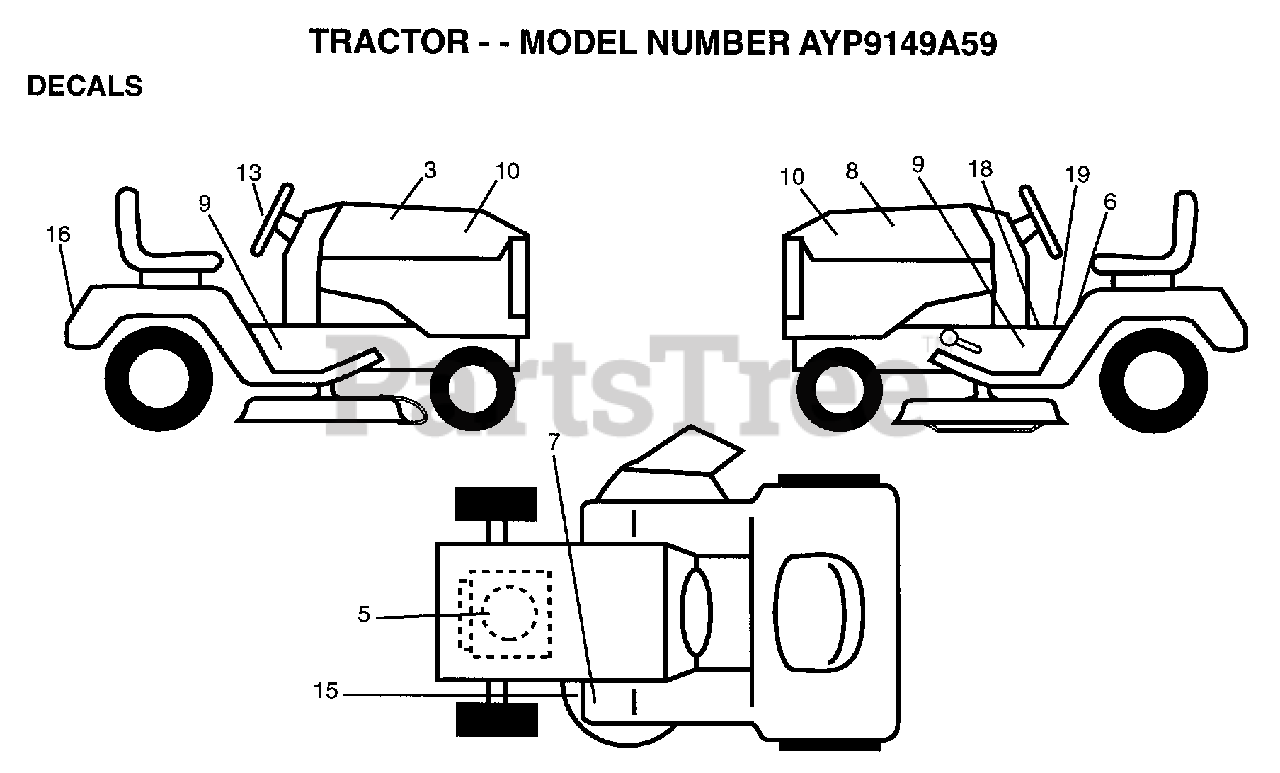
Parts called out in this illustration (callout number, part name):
3	DECAL.HD.RH.WIZAR
5	DECAL, ENGINE
6	DECAL
8	DECAL.HD.LH.WIZAR
9	"DECAL.CHASSIS.42"""
10	DECAL.INS.HD.14.5
13	DECAL.INS.STRG.WL
15	DECAL
18	DECAL SADLE HYDRO
